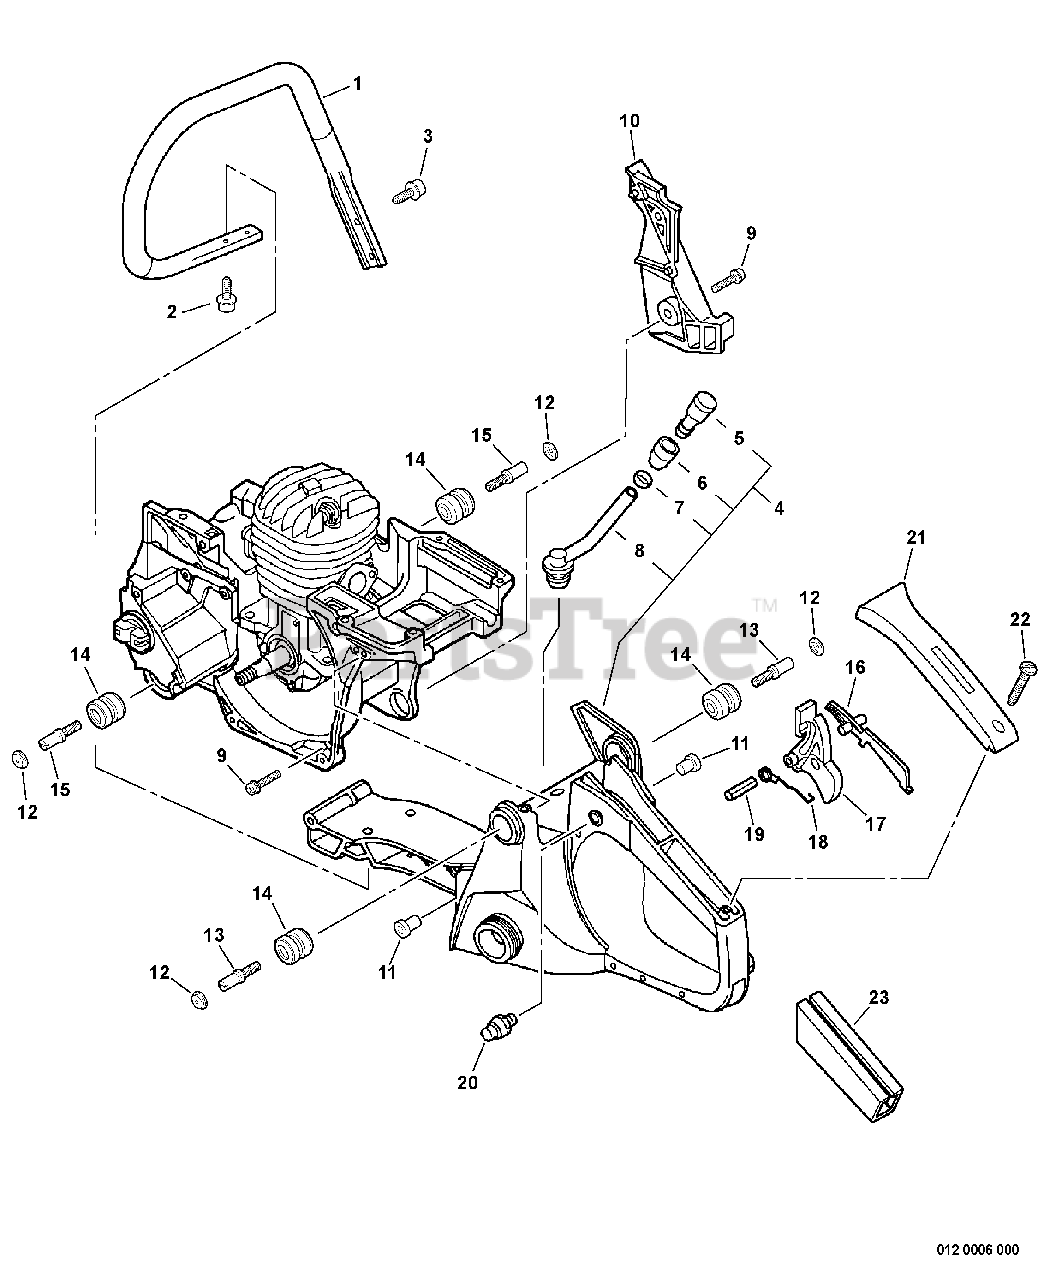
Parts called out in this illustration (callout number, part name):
1	HANDLE - FRONT
2	SCREW - 5X16
3	SCREW - 5X20 -- TAPPING
4	HANDLE ASSY - REAR
5	VENT, FUEL TANK
6	COVER, VENT
7	CLIP - 6.5
8	PIPE - VENT
9	SCREW - 5X16
12	CAP, CUSHION
16	LEVER, TRIGGER LOCKOUT
17	TRIGGER, THROTTLE
18	SPRING, TRIGGER
19	PIN - SPRING -- 4X30
20	LATCH, THROTTLE
21	COVER, HANDLE
22	SCREW - 4X14
23	GRIP, HANDLE
